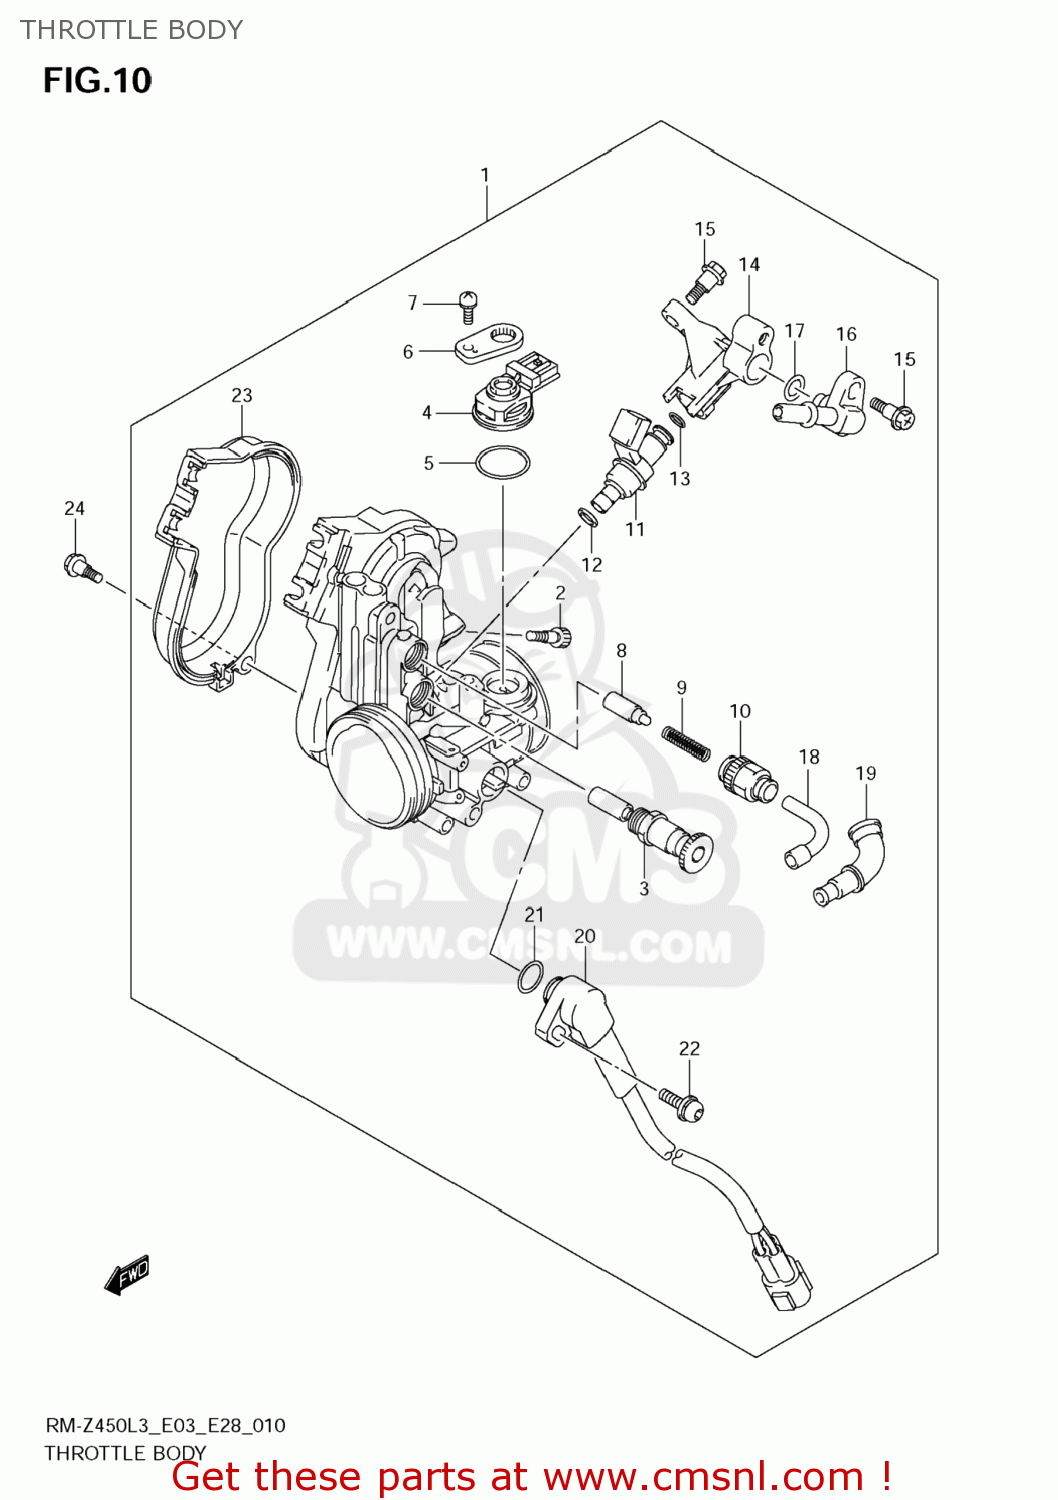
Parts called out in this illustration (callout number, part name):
1	BODY ASSY,THROTTLE
2	SCREW
3	STARTER
4	SENSOR,MAP
5	O RING
6	PLATE,STAY
7	SCREW
8	VALVE,STARTER
9	SPRING
10	HOLDER,CABLE
11	INJECTOR ASSY
12	RING,SEAL
13	O RING
14	PIPE,FUEL
15	SCREW
16	JOINT
17	O RING
18	GUIDE,CABLE
19	CAP
20	SENSOR ASSY,THROTTLE
21	O RING
23	COVER
24	SCREW
